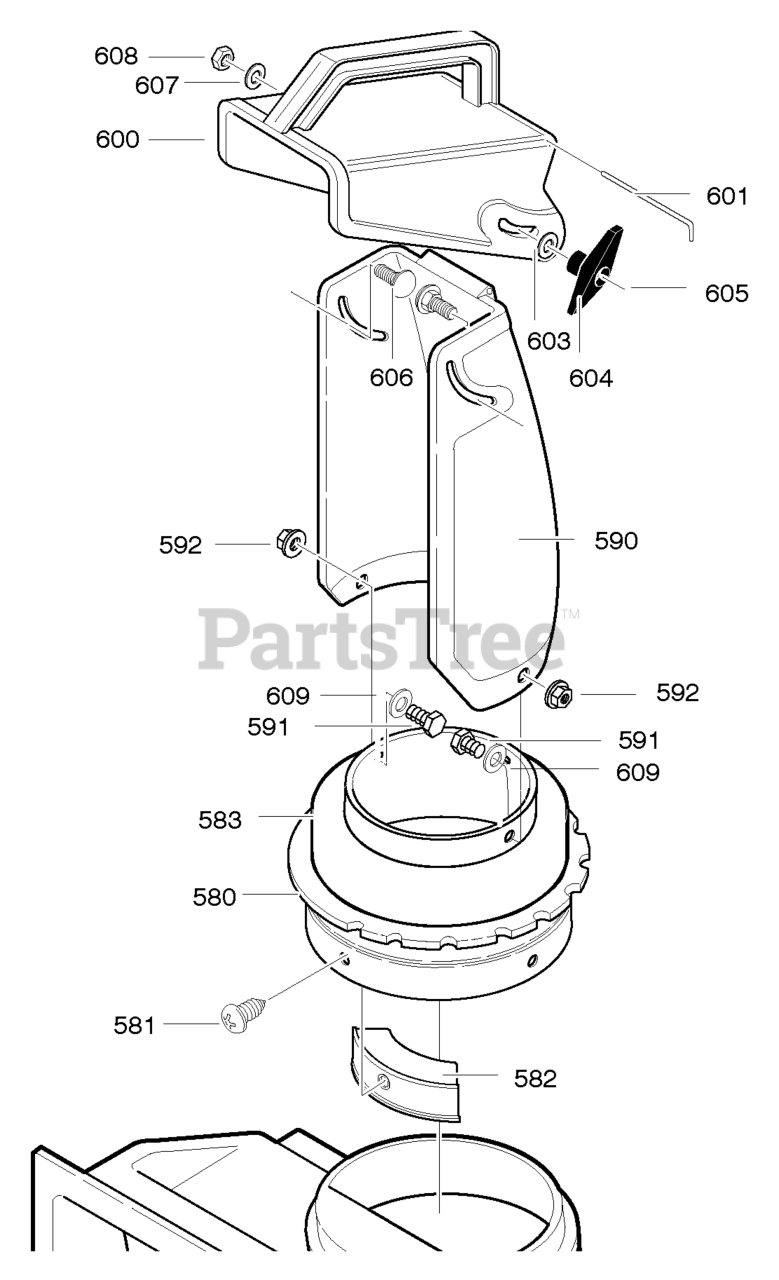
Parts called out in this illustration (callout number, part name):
580	RING, CHUTE
582	GUIDE, CHUTE
583	DONUT, FOAM
590	CHUTE, LOWER
591	SCREW, 1/4-20X .75
592	NUT, 1/4-20
593	WASHER, FLAT
600	CHUTE, UPPER WITH HANDLE
602	BOLT, 5/16-18X1.25
603	WASHER, FLAT
604	T-KNOB
605	NUT, 5/16-18
606	SCREW, 5/16-18
607	WASHER, FLAT
608	NUT, 5/16-18
609	WASHER, FLAT
